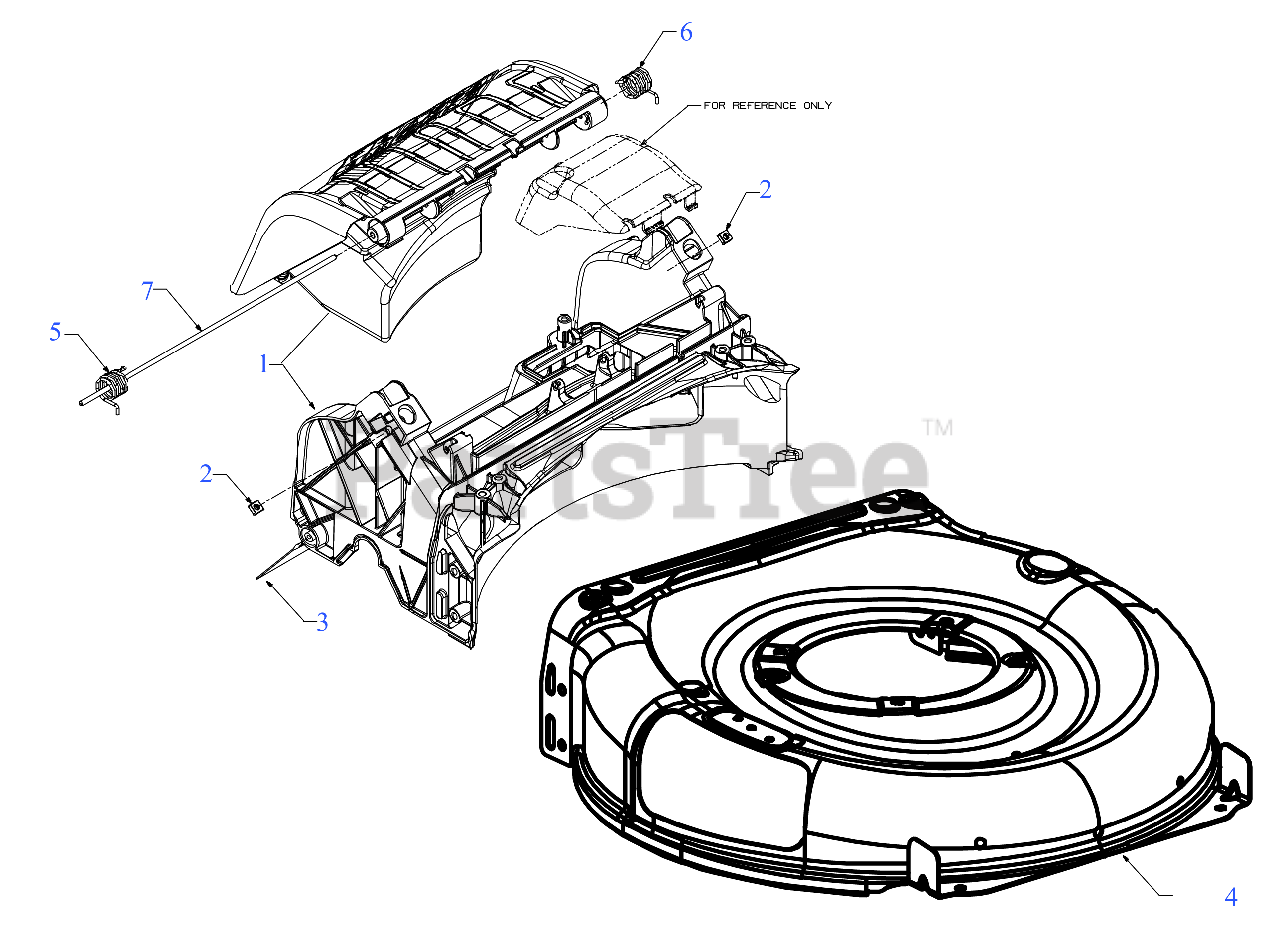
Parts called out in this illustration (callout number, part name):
1	REAR BAG BAFFLE ASSEMBLY
2	SQUARE NUT 1/4-20
3	TRAILSHIELD
5	TORSION SPRING (RH)
6	TORSION SPRING (LH)
7	REAR DOOR PIVOT ROD
